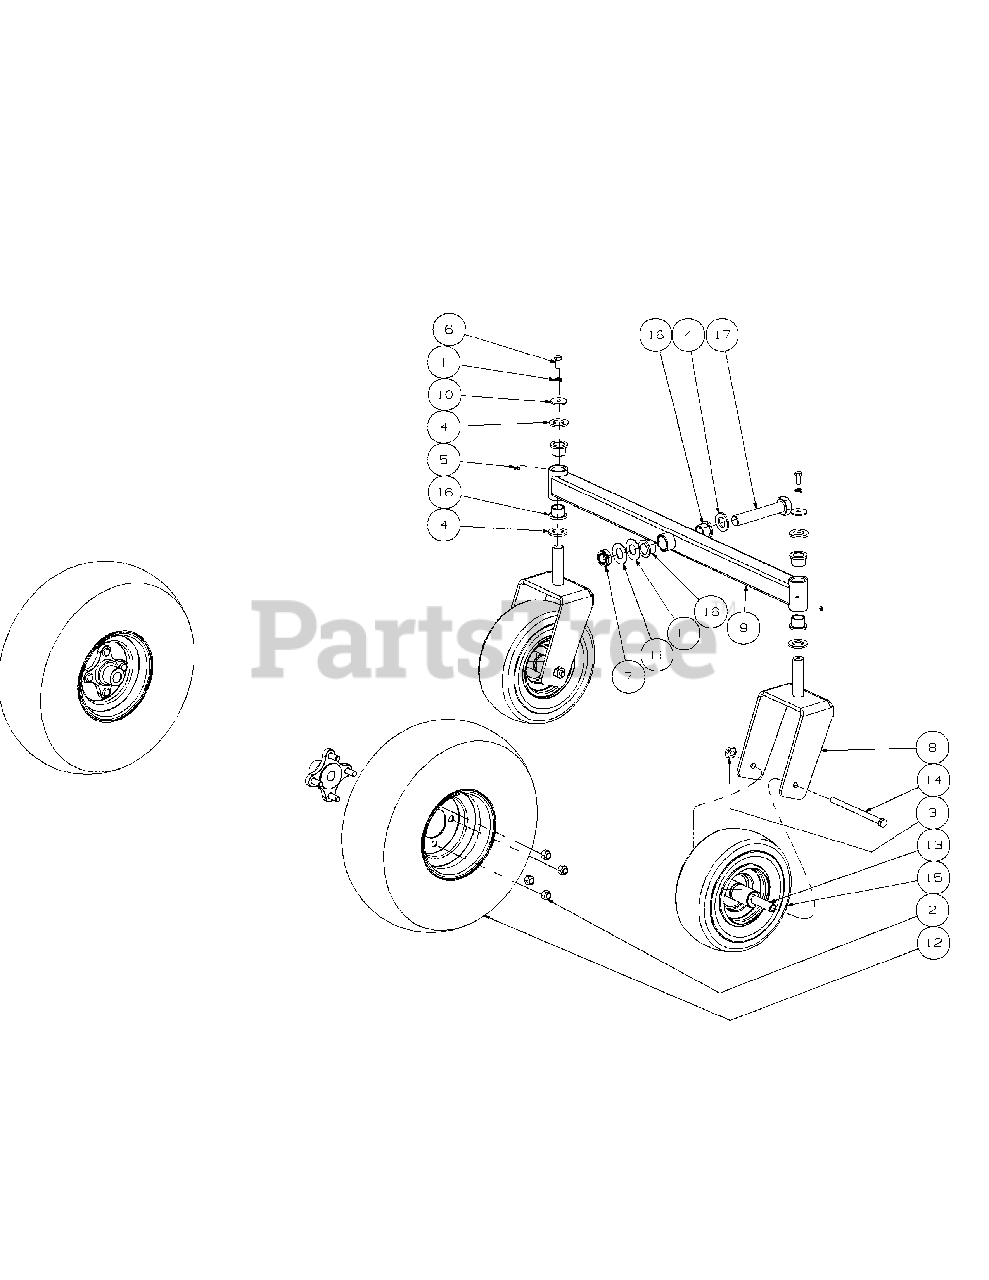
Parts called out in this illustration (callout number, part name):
1	Lock Washer, 3/8 Zinc
2	Lug Nut, 1/2-20
3	Lock Nut, Nylon Insert, 1/2-20
4	Washer Special
5	Grease Fitting, 1/4-28 x 3/16
6	Hex Cap Screw, 3/8-16 x .88
7	Nut Jam, 1.0-14, Nylon Insert
8	Castor Wheel Mounting Bracket
9	Front Axle Assembly
10	Flat Washer, .390 x 1.5 x .134
11	Flat Washer, 1.00 ID x 2.25 OD x ,075
12	Wheel Assembly, 20 x 8-10 NHS
13	Wheel Spacer
14	Hex Cap Screw, 1/2-20 x 7.50
15	Wheel Assembly 11 x 6.00 - 5, Beige
16	Flange Bearing, 1.001 x 1.25
17	Hex Cap Screw, 1-14 x 5.5
